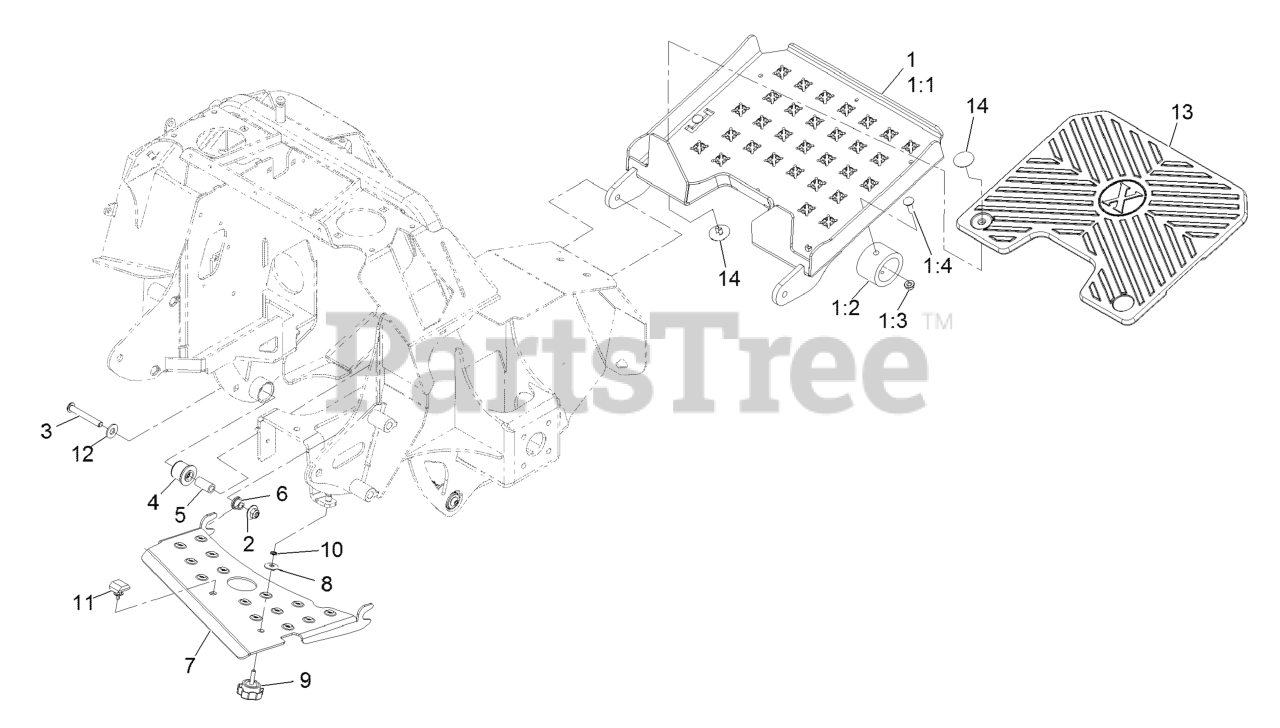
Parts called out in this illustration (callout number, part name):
1	ASM-PLATFORM
1:1	WELD-PLATFORM
1:2	BUMPER-ISOLATOR
1:3	NUT-HF, NI
1:4	BOLT-CARR
2	Nut-Nyloc 3/8-16 Flg
3	SCREW-HSBH
4	BUSHING-RUBBER, SUSPENSION
6	BUSHING-FLANGED
7	DEFLECTOR, AIR, 36
8	WASHER-BELLEVILLE
10	NUT-RETAINING
11	BUMPER-ROPS
12	WASHER-FLAT
13	PAD-PLATFORM
14	RIVET-RATCHET
